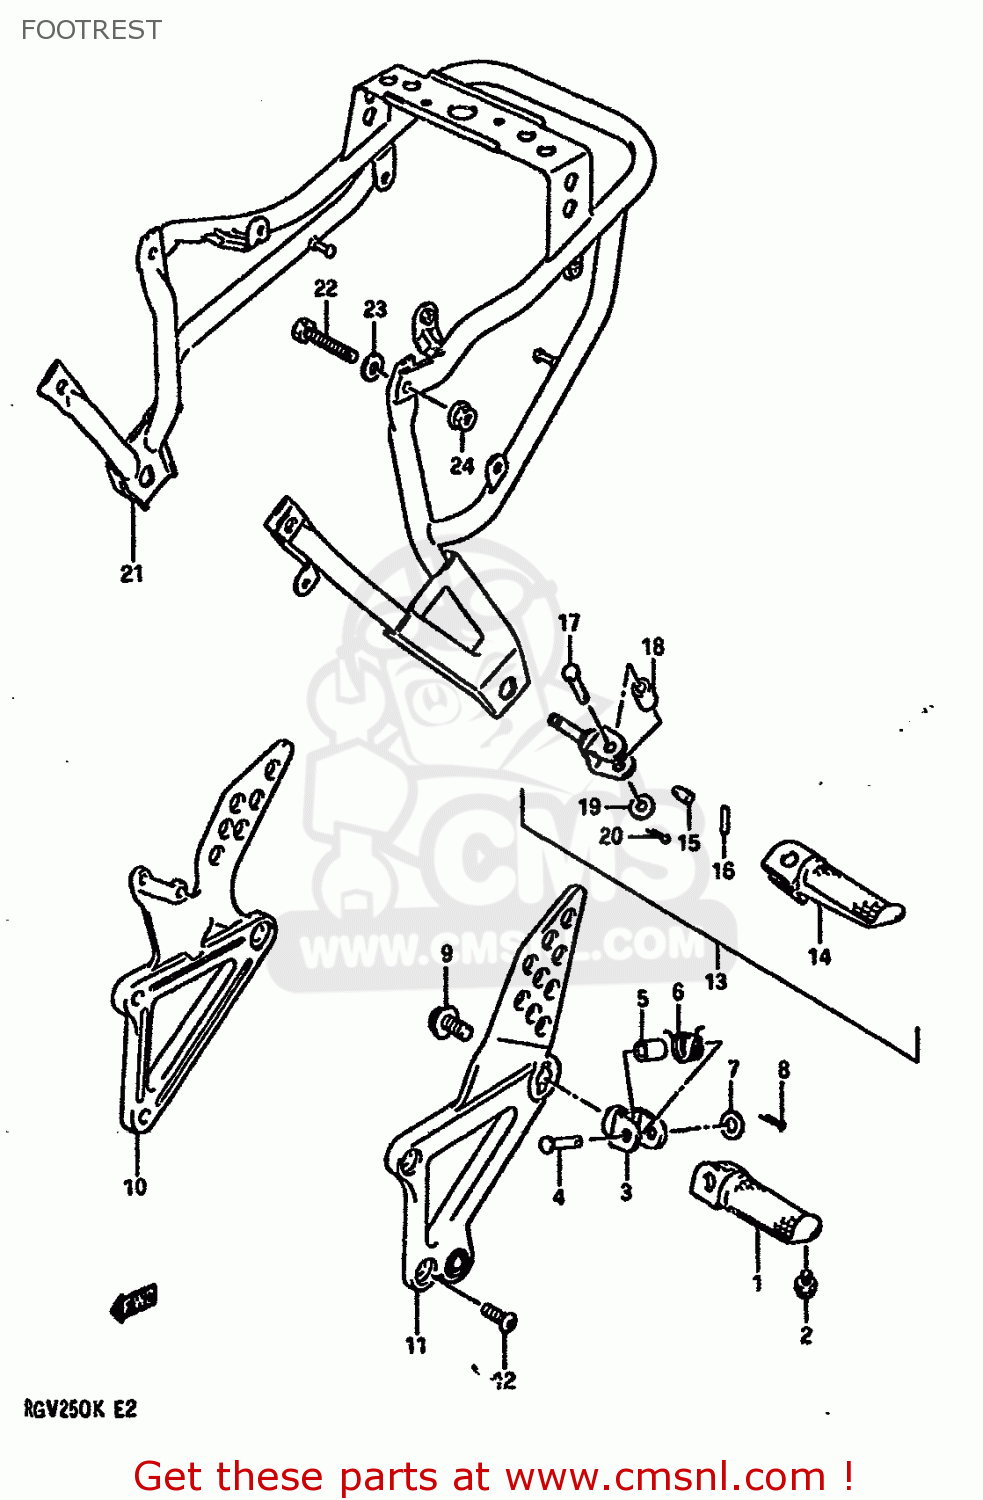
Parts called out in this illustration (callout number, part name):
1	BAR,FR FOOTREST,R
2	BOLT(6X6)
3	HOLDER,FOOTREST,R
4	PIN
5	SPACER(8.1X12X22)
6	SPRING
7	WASHER
8	PIN 20X15
9	BOLT(10X20)
10	BRACKET,FRONT FOOTREST R
11	BRACKET,FRONT FOOTREAR LH
12	BOLT(8X20)
13	FOOTREST ASSY,PILLION R
14	BAR,PILLION FOOTREST R
15	CUSHION,FOOTREST HOLDER
16	PIN(4X20)
17	PIN
18	SPACER(8.1X12X22)
19	WASHER
20	PIN 20X15
21	BRACKET,PILLION FOOTREST
22	BOLT 8X40
23	WASHER
24	NUT
